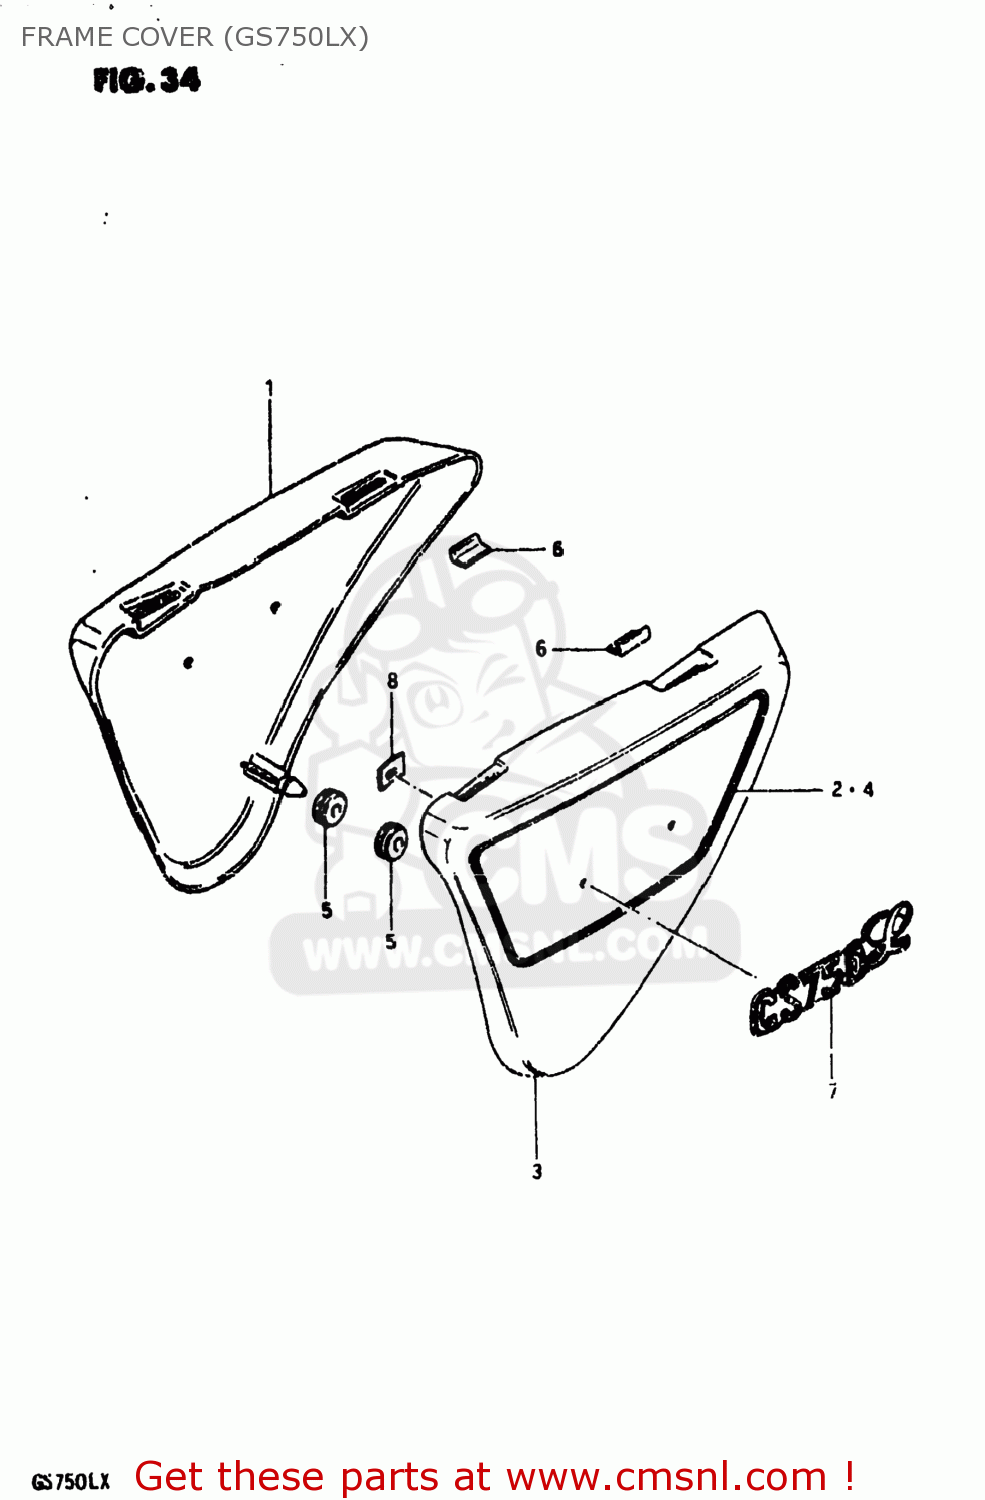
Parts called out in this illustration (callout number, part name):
1	COVER,FRAME,RIGHT
2	TAPE SET,FRAME COVER
3	COVER,FRAME,LEFT
4	TAPE SET,FRAME COVER
5	CUSHION
6	CUSHION,FRAME COVER
7	EMBLEM,FRAME COVER
8	NUT
